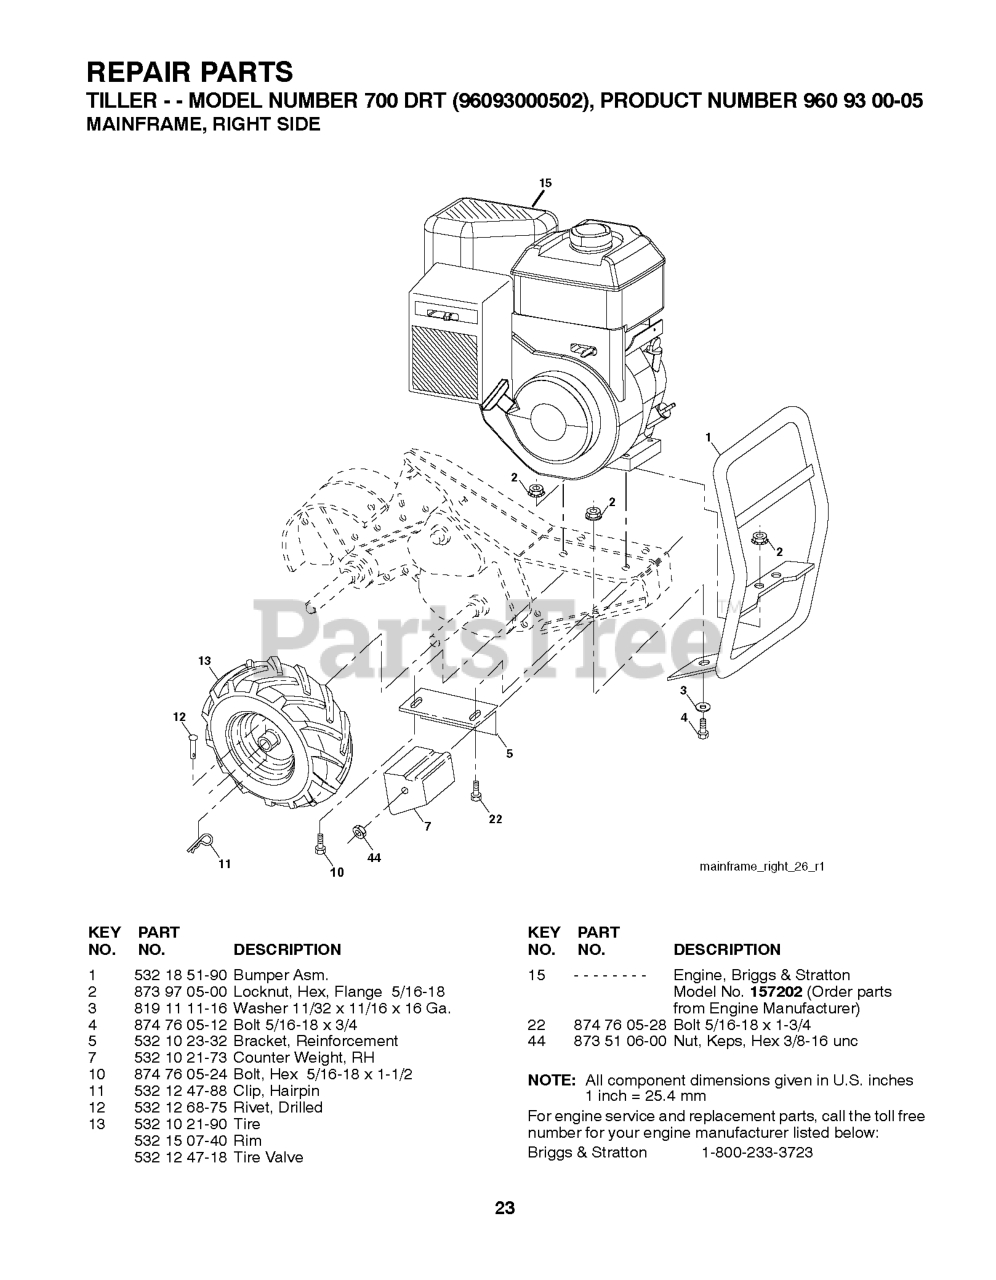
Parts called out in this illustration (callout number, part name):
1	RP.BUMPER.ASM.TILLER.
2	LOCKNUT-FLANGE 5/16-18
3	WASHER
4	BOLT
5	DNO BRACKET RH CRT
7	COUNTERWEIGHT, RH
10	BOLT
11	RETAINER M
12	RIVET,DRILLED
13	TIRE.13X5-6.CHEVRON.TILLER
22	BOLT, HEX 5/16-18X1-3/4
